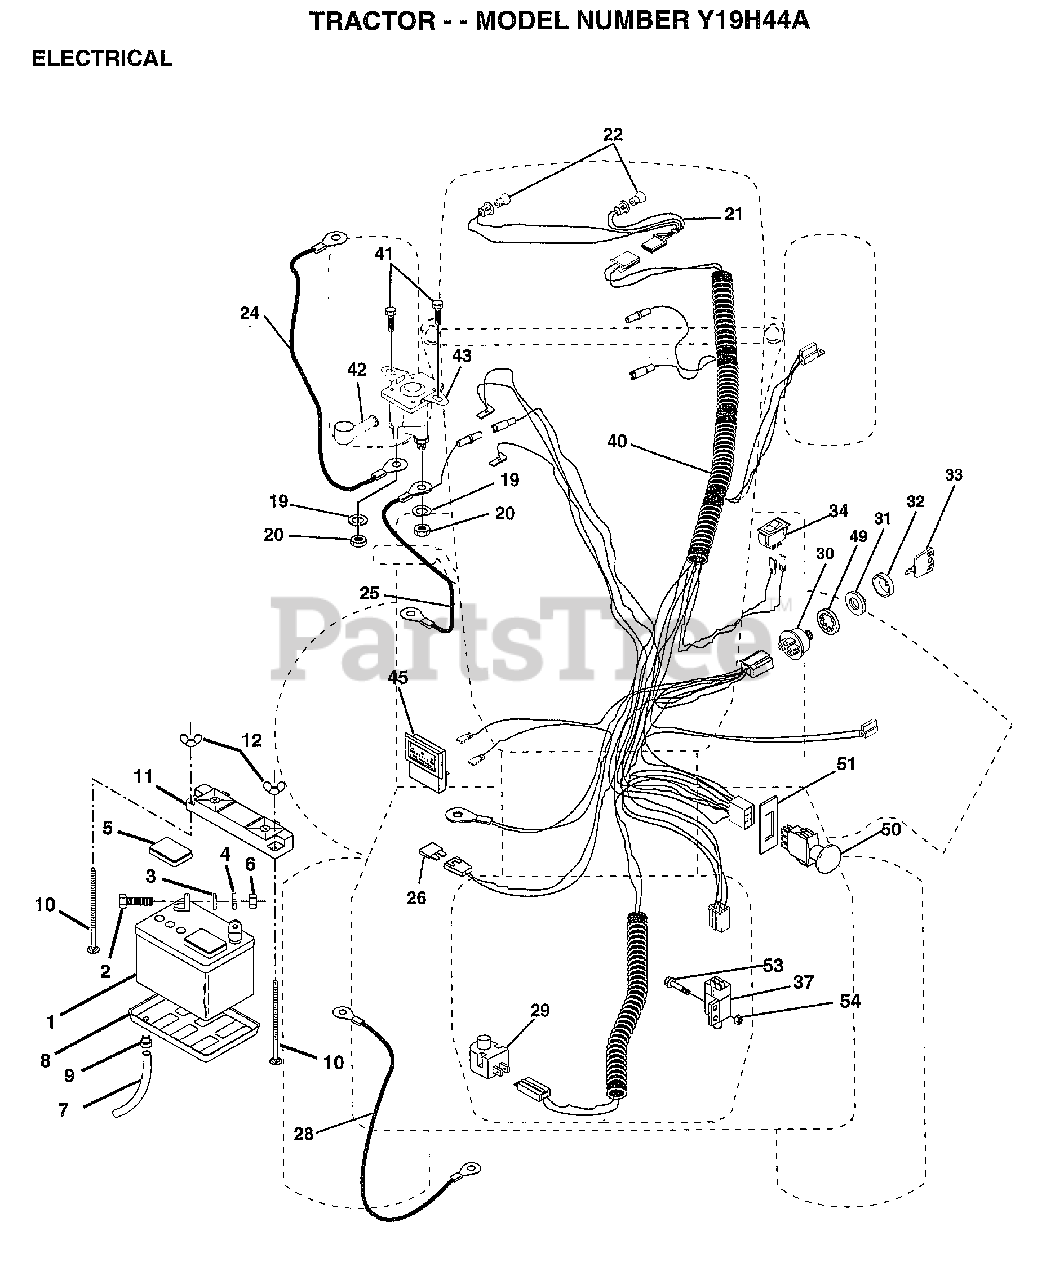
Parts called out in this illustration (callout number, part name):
2	BOLT LT
3	LOCKWASHER
4	WASHER
5	"CAP,BATTERY "
7	"DRAIN TU T, BATT"
8	"TRAY T, BATTERY"
9	HOSE CLAMP T
20	NUT
21	"HARNESS,LIGHT SOC"
22	HEADLAMP BULB
24	"CABLE T, BATTERY"
25	CABLE.6GA.12.5.
26	FUSE HYT
28	CABLE T
29	SWITCH SEAT
32	COVER KEY SWITCH
33	KEY MLD GEN DELTA
34	SWITCH LT
37	SWITCH INTERLOCKT
40	HARNESS.IGN.VGT.
41	SCREW
45	AMMETER
49	LOCKWASHER
51	RING RETAIN PTO
53	SCREW
54	"NUT,KEPS"
